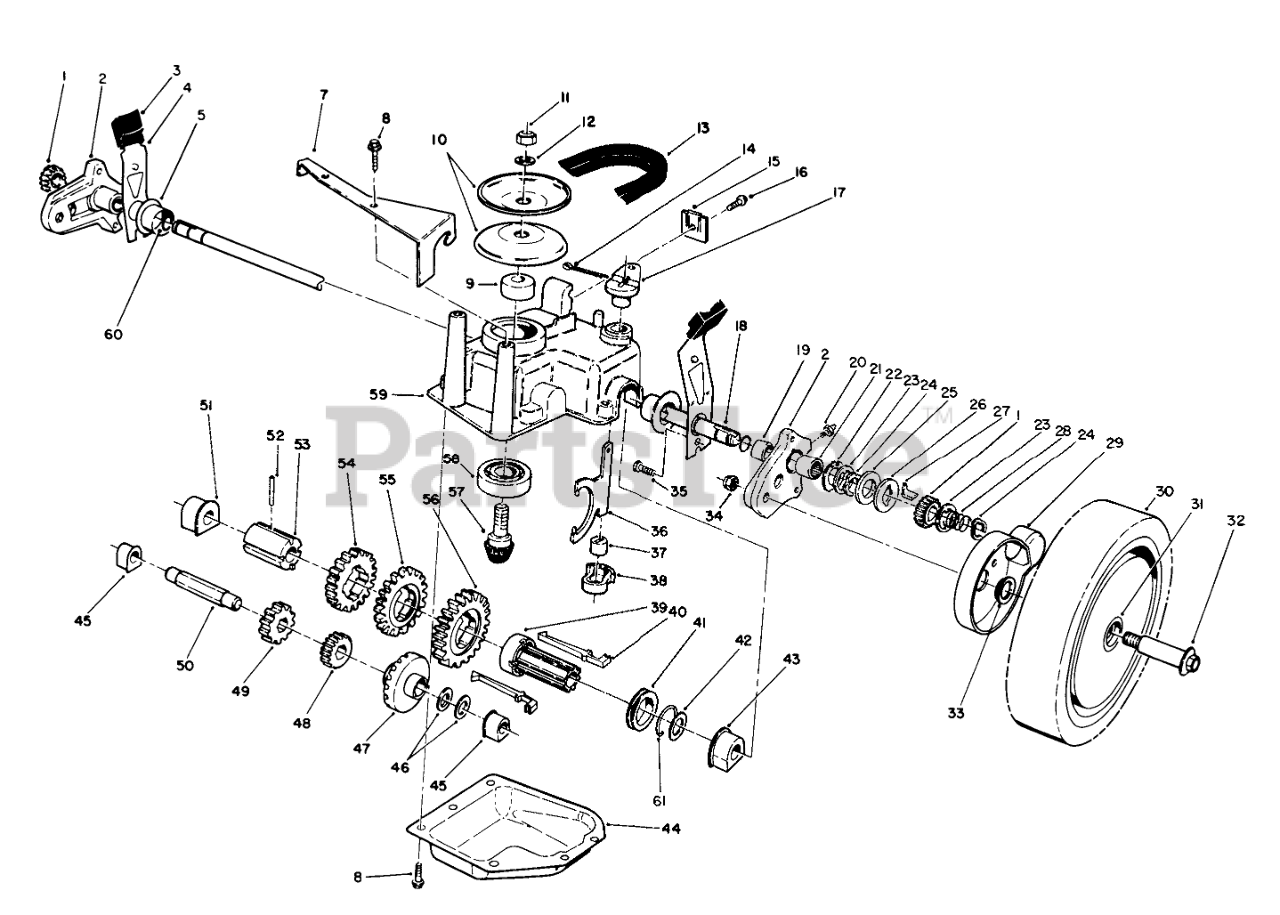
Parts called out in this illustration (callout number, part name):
1	GEAR-PINION
2	Pivot Arm Assembly (Incl. Ref. #19, 20, 21)
3	KNOB-ARM
4	SPRING ARM ASM SP
5	CAP-END
7	Bracket-Guide
8	SCREW-HWHTF
9	SPACER
10	Pulley Half
11	NUT-HEX
12	WASHER-FLAT
13	V-BELT E
14	PIN-COTTER
15	Cable Clamp
16	SCREW-HWHTF
17	SHIFT LEVER
18	SHAFT-OUTPUT
19	BUSHING
20	FITTING-GREASE
21	BEARING-ROLLER
22	WASHER-ARM, PIVOT
23	WASHER-THRUST, KEYED
24	RING-CLIP, LOCKING
25	RING-FRICTION
26	WASHER-CLUTCH
27	KEY-ROCKING, LH
28	SPRING-COMPRESSION
29	COVER-WHEEL
30	Wheel-Tire & Gear Assy. (Incl. Ref. #31)
31	BUSHING
32	WHEEL BOLT
33	SPACER-COVER, WHEEL
34	Nut
35	SCREW-HWH
36	YOKE-SHIFT
37	BUSHING-YOKE
38	RETAINER-FORK, SHIFT
39	SLEEVE-KEY, SHIFT
40	KEY-SHIFT
41	COLLAR-SHIFT
42	WASHER-PLAIN
43	BUSHING-OUTPUT
44	Cover-Gearcase
45	BUSHING
46	WASHER-THRUST
47	Gear-Bevel
48	PINION-20T
49	PINION-25T
50	SHAFT-INTERMEDIATE
51	BUSHING
52	PIN-SPRING
53	SLEEVE-GEAR
54	GEAR-39T
55	GEAR-44T
56	GEAR-49T
57	Gear-Pinion
58	BEARING-BALL
59	CASE-GEAR, UPPER
60	O-RING
61	CLIP-SPRING
